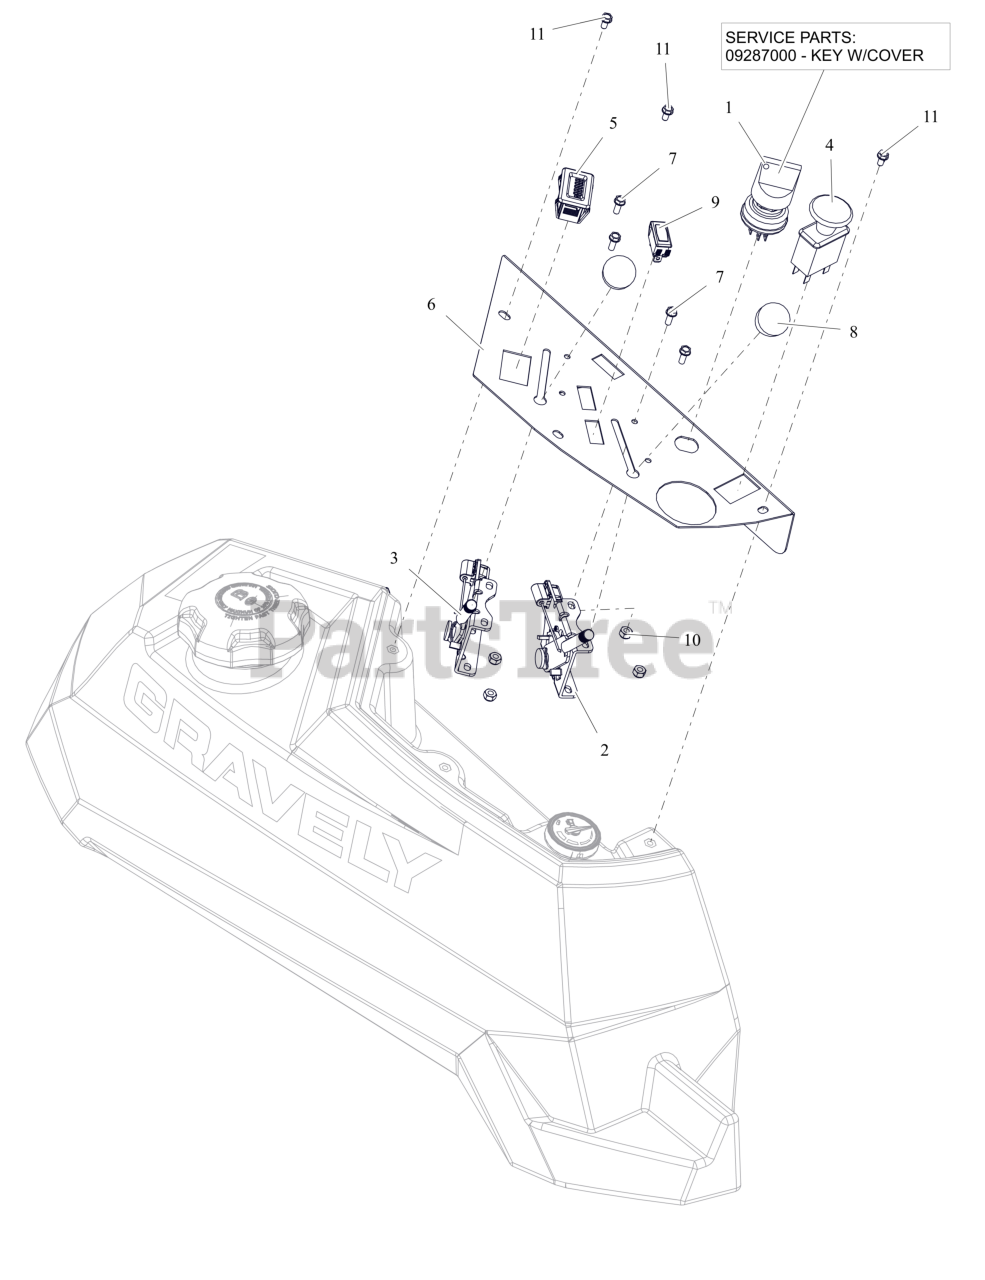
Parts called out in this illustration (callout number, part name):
1	SWITCH, IGNITION
1	KEY, W/ SHIELD
2	CABLE, PRO-CONTROL 28.50
3	CABLE, PRO-CONTROL 31.50"
4	SWITCH, CLUTCH
5	HOUR METER
6	PT100 CONTROL PANEL - RED
7	BLT, HWH #10-24X.50 ZCC
8	KNOB-CONTROL-BLACK .38-16X.50
9	LIGHT, INDICATOR (RED)
10	NUT-LK-NYL #10-24 G2 ZCC
11	SCR-MCH 10-24X.38 HWHSTAINLESS
